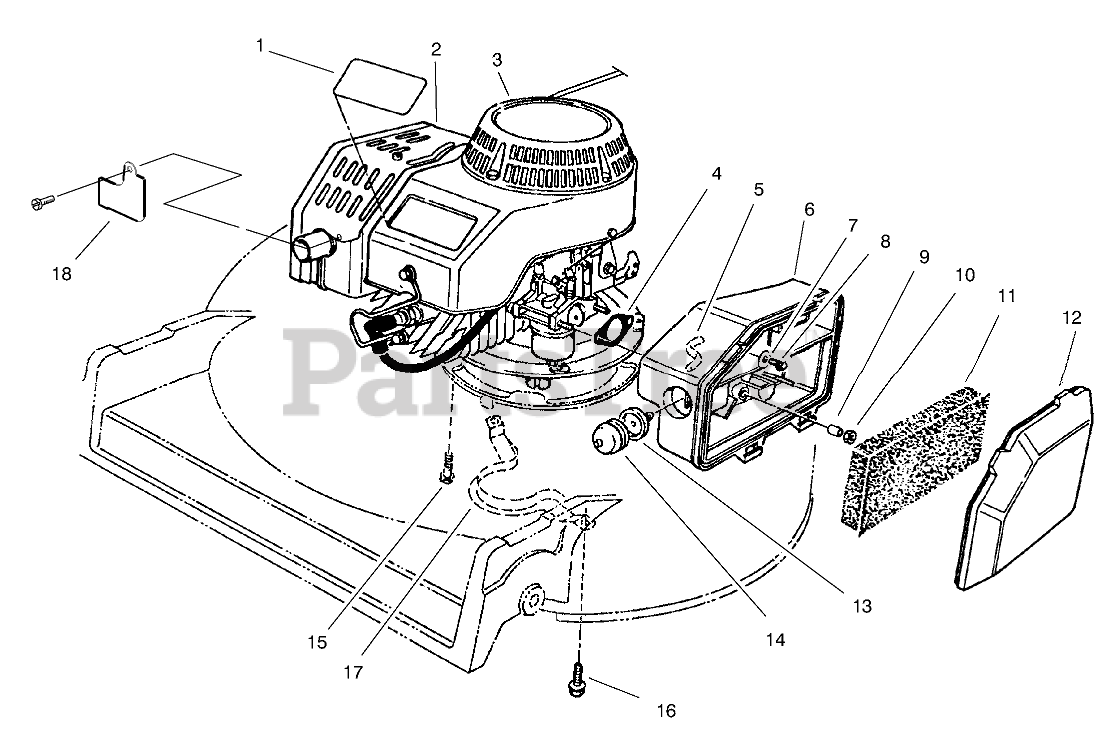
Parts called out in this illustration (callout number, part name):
1	DECAL - PROLINE
2	ENGINE ASM - BBC 2 CYCLE
3	DECAL-2 CYC RECOIL COMM
4	GASKET-AIR CLEANER
5	HOSE-PRIMER
6	BODY-AIR CLEANER
7	WASHER-FLAT
8	SCREW-HH
9	SPACER
11	ELEMENT-AIR CLEANER
12	COVER-AIR CLEANER
13	BODY-PRIMER
14	BULB-PRIMER
15	SCREW-HHF
16	SCREW-HWHTF
17	Guide-Belt
18	EXTENSION-MUFFLER GUARD
